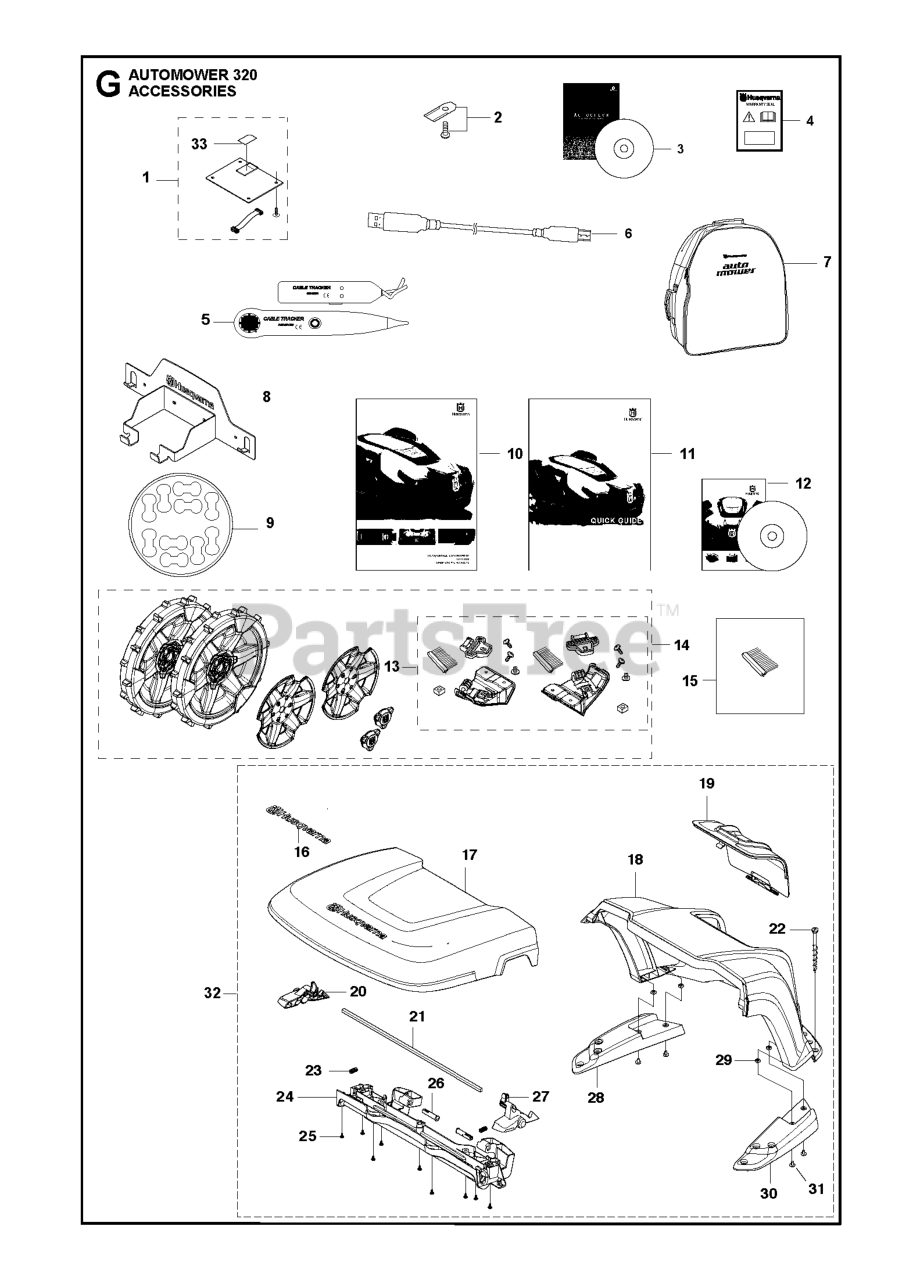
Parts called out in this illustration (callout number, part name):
2	BLADE SET 300 PCS. CARBON STEE
2	BLADE KIT HUSQVARNA 9 PCS 50HR
2	BLADE SET 45 PCS
3	DVD AUTOCHECK EXP SERVICE
4	LABEL WARRANTY SEAL KIT 10 PK
4	LABEL WARRANTY SEAL DEALER
5	TEST EQUIPMENT
6	CABLE WHITE ALT GREY
9	STICKER CABLE MARKERS KIT 10PC
12	CD DVD MANUALS 305, 308, 310,
14	REAR WHEEL KIT W/ BRUSHES
16	DECAL.HUSQVARNA.210MM
17	KIT LID - AUTOMOWER HOUSE
18	COVER BASE P2 HOUSE
20	HANDLE RELEASE LEFT
22	SCREW KIT CS
23	SPRING SPRING CAP
25	SCREW 14MM
26	HINGE PIN
27	HANDLE RELEASE RIGHT
28	SUPPORT BASE LEFT
29	NUT
30	SUPPORT BASE RIGHT
31	SCREW IHPANM M6X25 4.6 ZP-BC
32	430/450 HOUSE KIT
